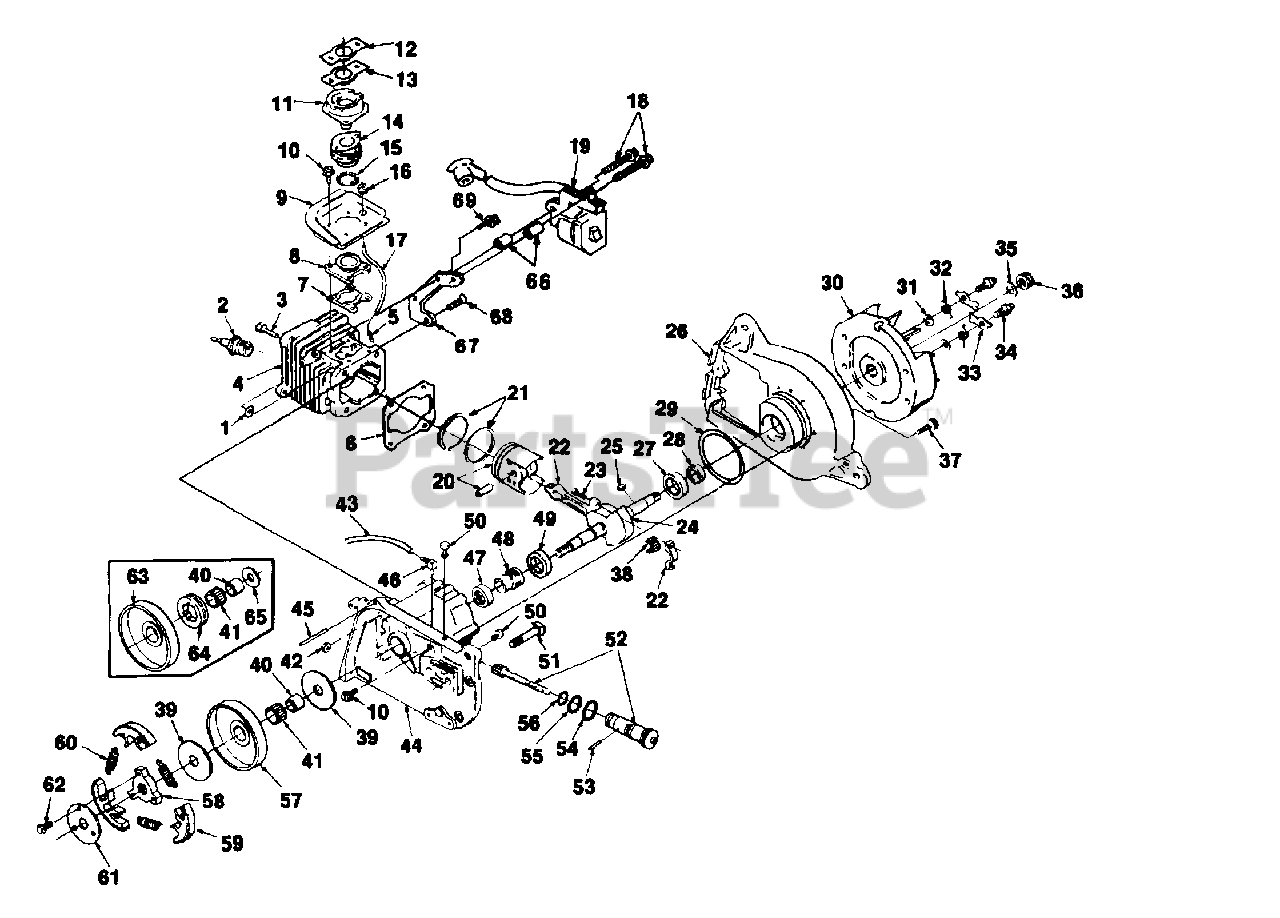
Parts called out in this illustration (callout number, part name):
2	SPARK PLUG (Champ. CJ6)
3	SCREW- Soc. hd. cap (#10-24 x 7/8")
4	CYLINDER
5	FITTING
6	GASKET- Cylinder
7	GASKET- Intake adaptor
8	MANIFOLD- Intake
9	DEFLECTOR- Air (Intake)
10	SCREW- w/Washer (8-32 x 1/2")
11	FLANGE- Carburetor connector
12	BUSHING & GASKET ASSY.
14	CONNECTOR- Carburetor
15	SPRING- Garter
16	GROMMET
17	LINE- Pulse (5 1/2")
18	SCREW- Hex sems (10-24 x 1.125")
19	MODULE & CORE
20	PISTON & PIN
21	PISTON RING
22	ROD- Connecting
23	SCREW- Soc. hd (8-32 x 9/16")
24	CRANKSHAFT
25	KEY- Woodruff
26	PLATE- Back
27	BEARING- Roller
28	SEAL
29	"O" RING
31	WASHER- Lock (#10)
32	SPRING- Starter pawl
33	PAWL- Starter
34	STUD- Starter pawl
35	WASHER- (3/8")
36	NUT- (3/8-24)
37	SCREW- Hex sems (10-24 x 3/4")
38	ROLLERS- Needle (Set of 25)
39	WASHER- Thrust
40	RACE- Inner
41	BEARING- Needle
42	NUT- Centerlock (#10-24)
43	TUBING- Rubber (Oil) 10 1/2"
44	CRANKCASE
45	PIN- Dowel
46	FITTING- Oil line
47	SEAL- (Double lip)
48	WORM GEAR
49	BEARING- Roller
51	BOLT- Guide bar (5/16")
52	PUMP- Automatic oil
53	PIN- Pump
54	"O" RING
55	"O" RING
56	"O" RING
57	SPROCKET & DRUM (7T, 3/8P)
58	SPIDER- Clutch
59	SHOE- Clutch
60	SPRING- Extension
61	COVER- Clutch
62	SCREW- Hex sems (8-32 x 3/8")
63	DRUM & HUB
64	SPROCKET & RIM (7T, 3/8P)
65	WASHER- Thrust
66	SPACER- Module
67	PLATE- Module mounting
68	SCREW- Flat hd. torx
69	SCREW- Hex (8-32 x 1/2")
